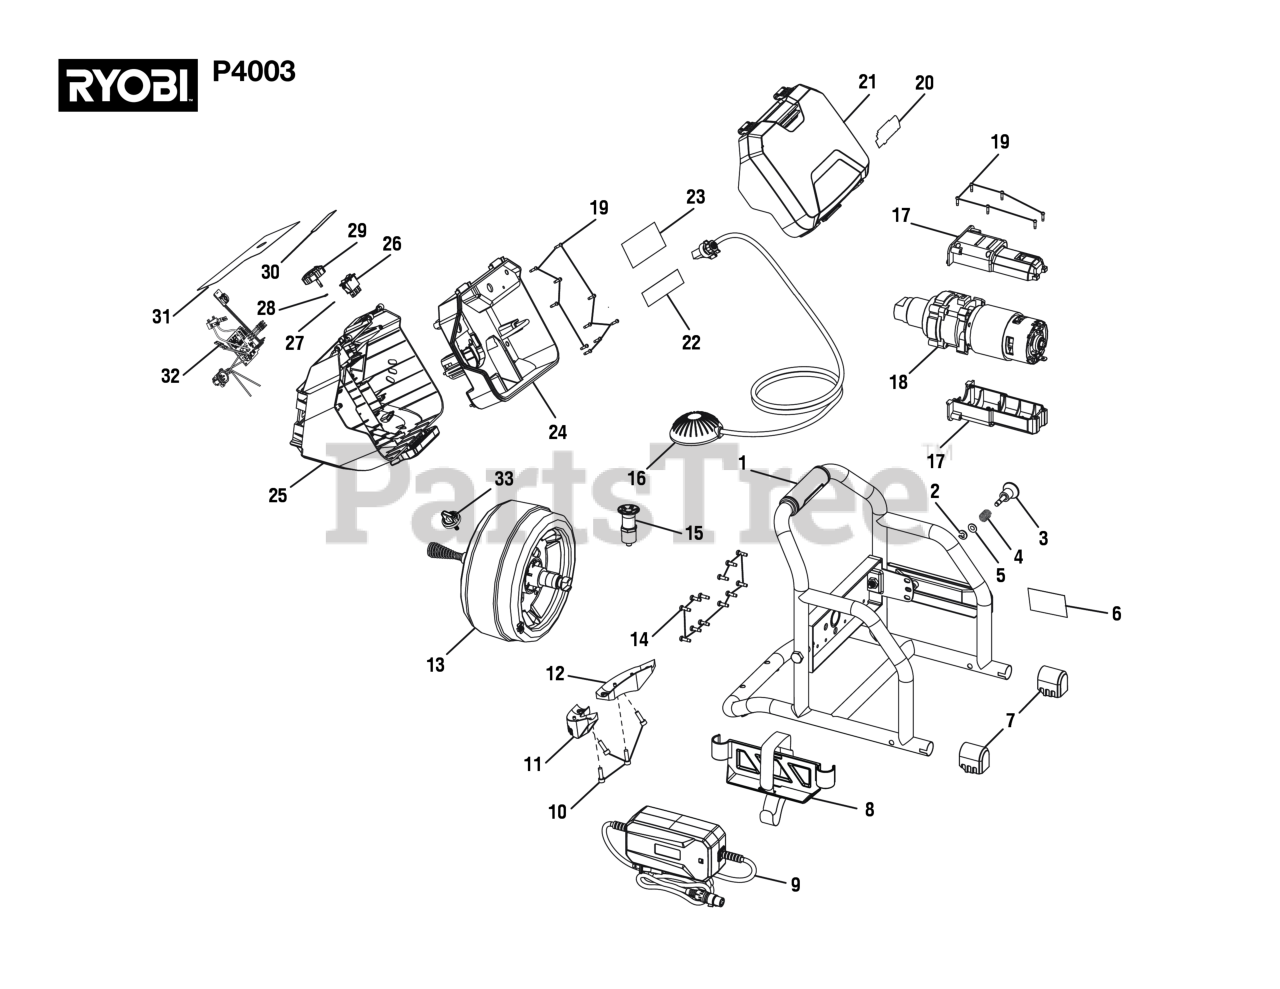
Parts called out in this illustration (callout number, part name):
1	Frame Assembly
3	Drum Angle Adjustment Knob
4	Compression Spring
5	Washer (OD16 x ID8.1 x 0.5t)
6	Logo Label
7	Foot (Back)
8	Bracket w/Power Supply Straps
9	Power Supply
10	Screw (M6 x 16 mm, Hex Soc. Hd.)
11	Foot (Right)
12	Foot (Left)
13	Drum and Cable Assembly
14	Screw (M4 x 12 mm, T20 Torx Pan Hd.)
15	Drum Retention Knob Assembly
16	Foot Pedal Assembly
17	Gear Train and Motor Housing Assembly
18	Motor and Gear Train Assembly
19	Screw (M3.5 x 16 mm, T10 Torx Pan Hd.)
20	Lithium-Hybrid Label
21	Battery Compartment Cover
22	Data Label
23	Warning Label
24	Housing Cover w/Elastic Band
25	Housing Support w/Latch
26	Direction of Rotation Switch (Forward/Reverse)
29	Variable Speed Control Dial
30	Direction of Rotation Label (Forward/Off/Reverse)
31	Scale Label
32	Circuit Board and Contact Plate Holder Assembly
33	Cable Lock Dial
